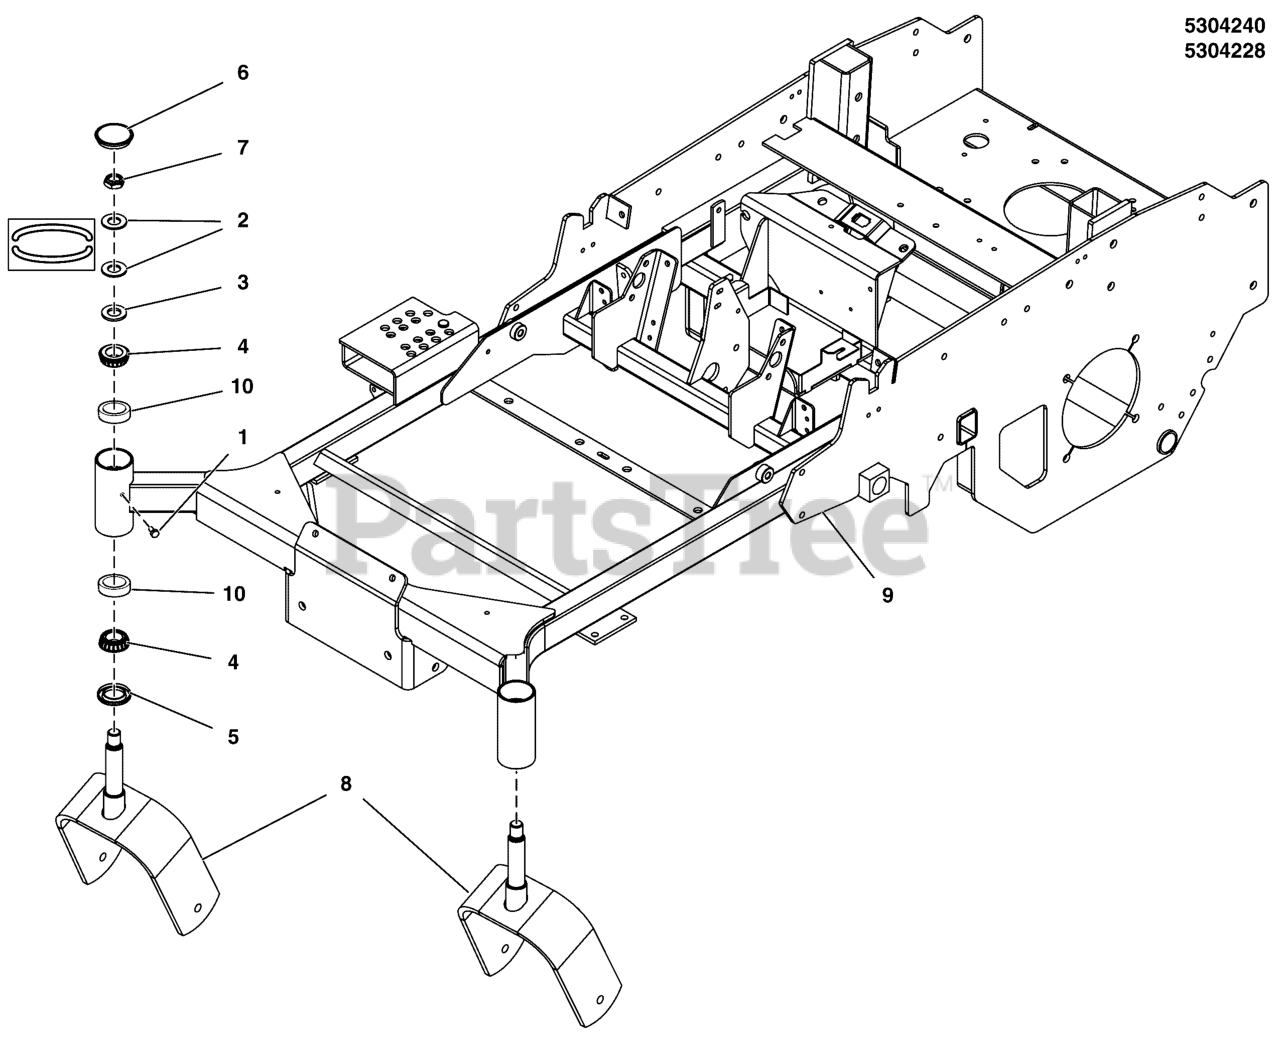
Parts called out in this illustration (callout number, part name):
1	BOLT, 1/4-28 X 1/2, GD5 CZ
2	WASHER, BELLEVILLE - 1.500 X .755
3	WASHER, 3/4 SAE
4	BEARING, TAPERED ROLLER, 1
5	SEAL, GREASE
6	CAP, GREASE, LOW PROFILE
7	NUT, 3/4-16, HEX JAM NYLON LOCK
8	WELD, CASTER YOKE - RED
9	* WELD, MAIN FRAME, F160Z - RED
10	CUP, BEARING
